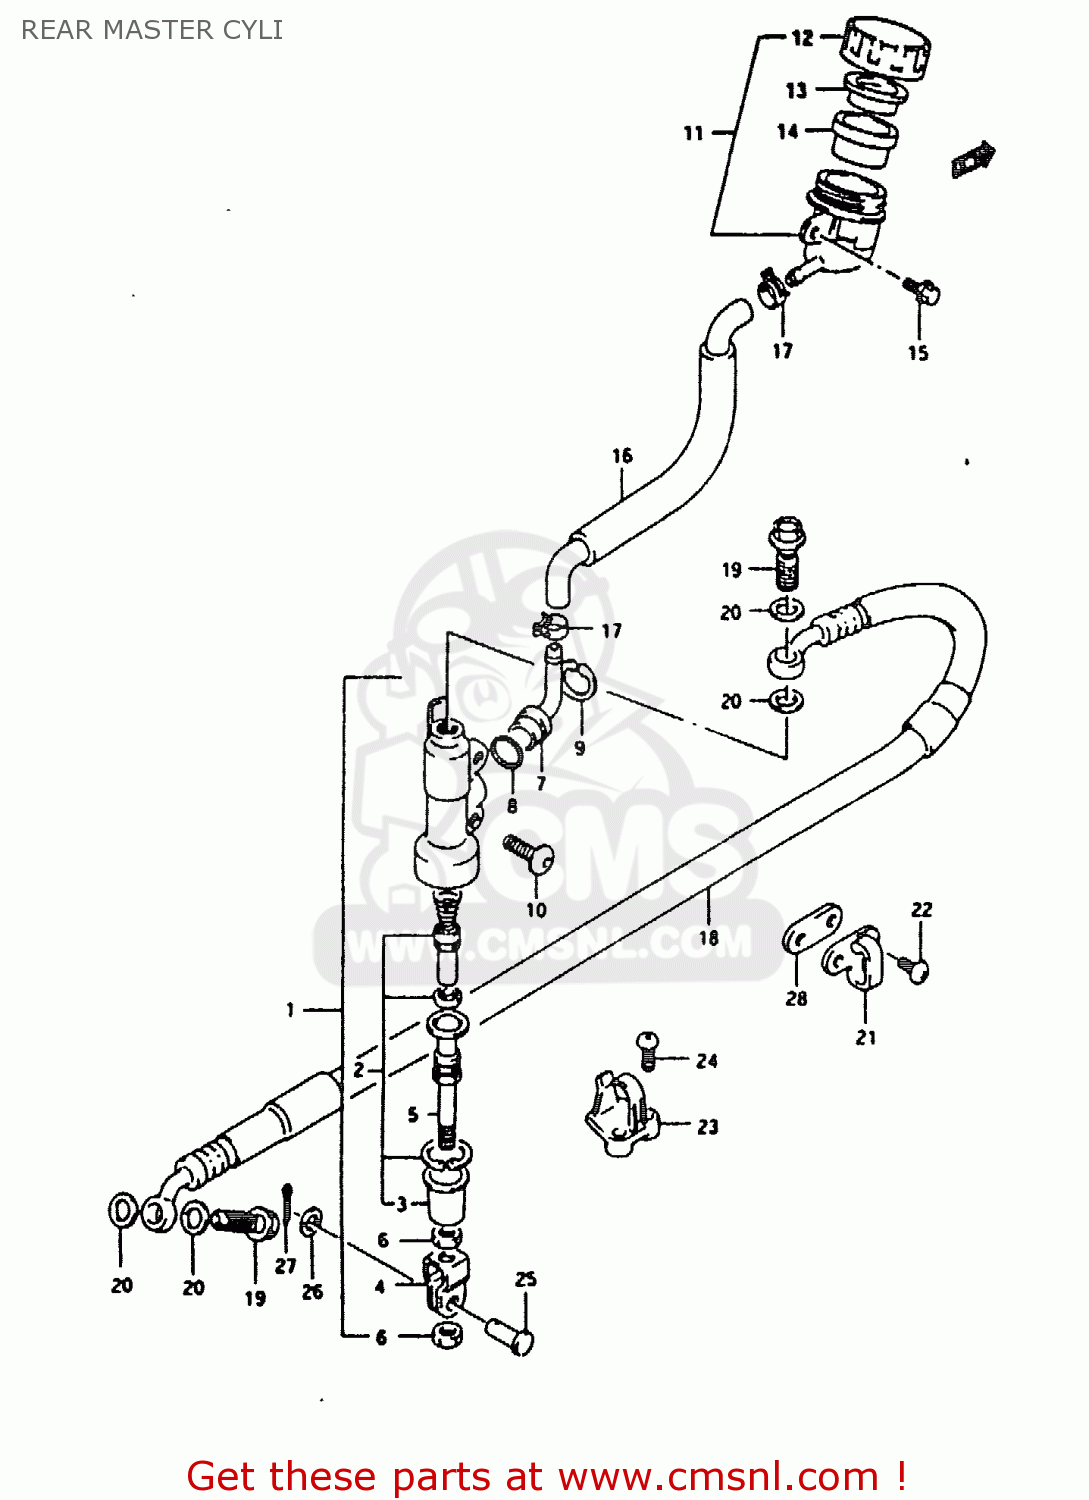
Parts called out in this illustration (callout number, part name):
1	CYLINDER ASSY, REAR MASTER
2	PISTON/CUP SET
3	BOOT
4	YOKE
5	ROD,PUSH
6	NUT
7	CONNECTOR
8	O RING
9	CIRCLIP
10	SCREW(6X16)
11	TANK ASSY,RR BRAKE RESERVOIR
12	CAP
13	PLATE
14	DIAPHRAGM
15	BOLT
16	HOSE,TANK
17	CLAMP,RESERVOIR HOSE
18	HOSE,RR BRAKE
19	BOLT UNION
20	WASHER(10X15X1.5)
21	GUIDE,RR BRAKE HOSE
22	SCREW
23	GUIDE, BRAKE HOSE, REAR
24	SCREW
25	PIN(8X20)
26	WASHER
27	PIN
28	SEAT,RR BRAKE HOSE GUIDE
